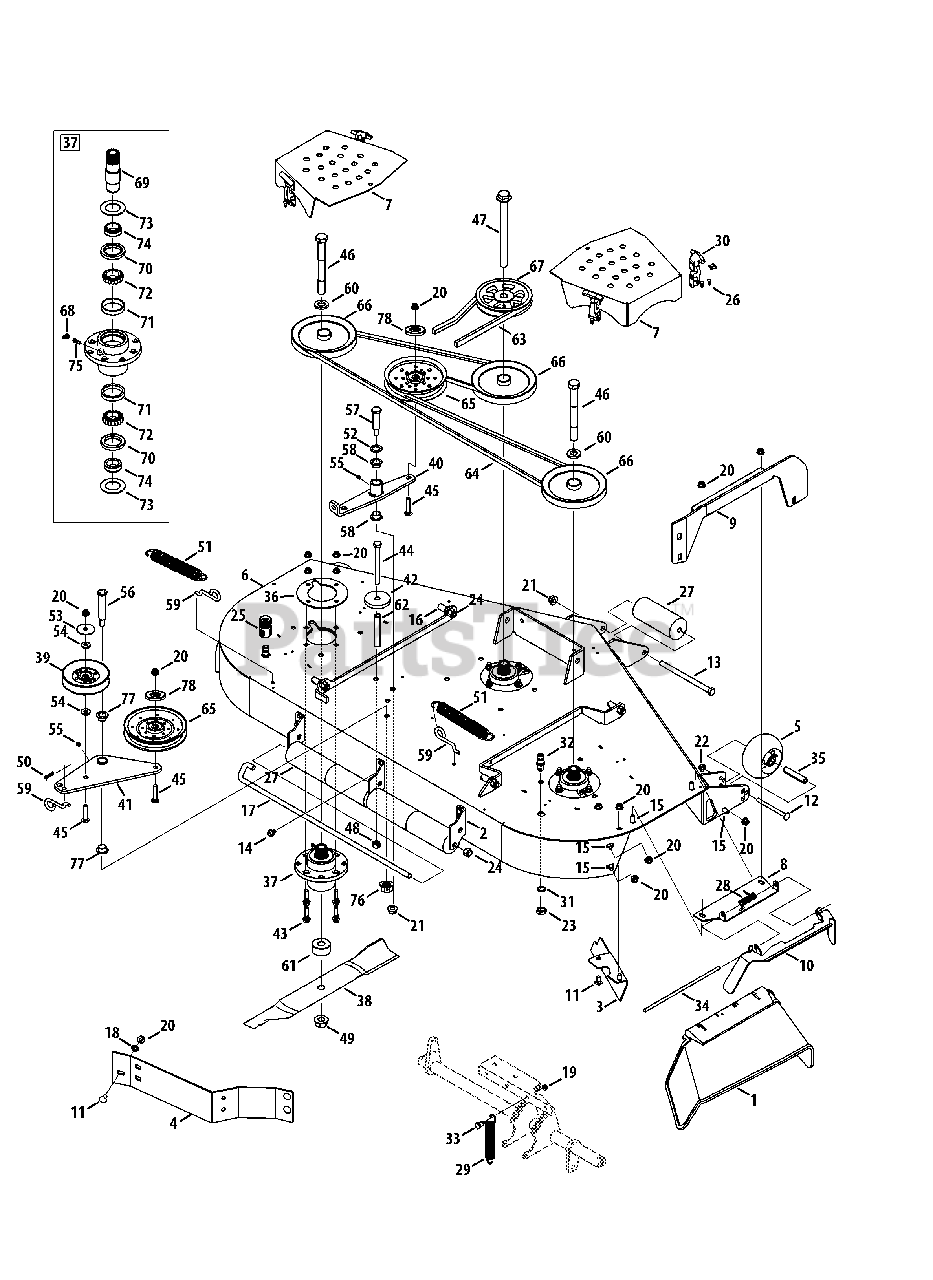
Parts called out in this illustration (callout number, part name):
1	Chute Deflector
4	Baffle, 60" Adjustment
5	Complete Wheel, 5.00 Dia.
6	60" Deck
7	Deck Belt Cover
8	Chute Deflector Bracket
9	Deck Support Plate
10	Chute Extension Bracket
11	Carriage Bolt, 3/8-16 x .750
12	Carriage Bolt, 3/8-16 x 4.00
13	Hex Cap SCrew, 1/2-13 x 7.50
14	Screw, 3/8-16 x .500
15	Carriage Bolt, 3/8-16 x 1.00
16	Pin, 1/2-13 x .625 x 1.2
17	J-Hook w/ Threaded Roller
18	Push Nut, 3/8
19	Nut, 1/4-20, Flangelock
20	Nut, 3/8-16, Flangelock
21	Nut, 1/2-13, Flangelock
22	Nut, 3/8-16, Centerlock
23	Hex Nut, M16-1.5
24	Nut, 1/2-13, Hexlock
25	Water Nozzle Adaptor
26	Pop Rivet, 3/16
27	Front Roller
28	Torsion Spring, 0.639 x 2.16
29	Extension Spring, .969 x 6.180
30	T-Handle Latch Draw
31	Lock Washer, 17 x 23.8 x 1.95
32	Deck Water Nozzle
33	Shoulder Bolt, .437 x .50, 1/4-20
34	Chute Deflector Rod
35	Wheel Spacer
36	Spindle Support Plate
37	Spindle Assembly
38	Hi-Lift Blade, 21.0
39	Idler Pulley
40	Deck Idler Arm
41	Idler Assembly
42	Spacer, .5375 x 2.75 x .375
43	Carriage Bolt, 3/8-16 x 1.5
44	Hex Cap Screw, 1/2-13 x 5.00
45	Carriage Bolt, 3/8-16 x 2.00
46	Hex Cap Screw, 3/4-16 x 7.00
47	Hex Cap Screw, 3/4-16 x 9.00
48	Nut, 1/2-13, Hexlock
49	Nut, 3/4-16, Flangelock
50	Bow Tie Cotter Pin
51	Extension Spring, 1.248 x 8.5
52	Washer, .793 x 1.24 x .06
53	Washer, .406 x 1.92 x .060
54	Washer, .406 x 1.00 x .105
55	Grease Fitting
56	Shoulder Bolt, 1.0 x 3.15, 5/8-18
57	Shoulder Bolt, .750 x 2.23, 1/2-13
58	Flange Bearing, .75 x .52
59	Spring Rod Hook
60	Spacer, .812 x .218
61	Spacer, .760 x 2.00 x .925
62	Spacer, .405 x .75 x 3.875
65	Idler Pulley
66	Spindle Pulley
67	Drive Pulley
68	Grease Fitting, 45 degree, 1/4-28
69	Spindle Shaft
70	Seal, Oil
71	Cup Bearing
72	Cone Bearing
73	Washer, 1.50 x 2.52 x .075
74	Ring, Seal
75	Straight Adapter Fitting
76	Nut, 5/8-18, Flangelock
77	Flange Bearing, 1.00 x .75
78	Pulley Cap
